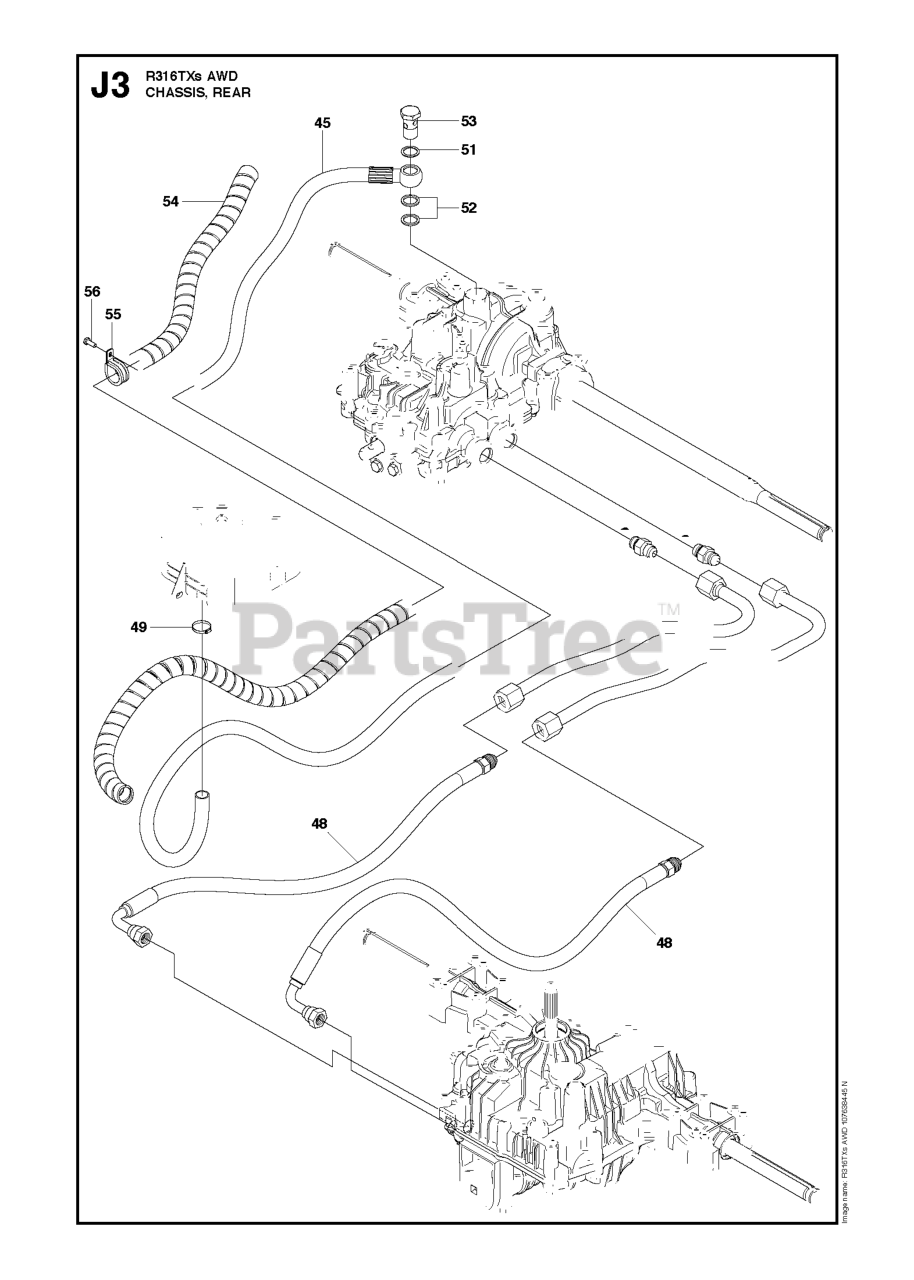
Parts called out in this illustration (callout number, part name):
45	HYDRAULIC HOSE
48	HYDRAULIC HOSE
53	PIPE FITTING
54	HOSE GUARD
55	HOSE CLAMP
56	SCREW
